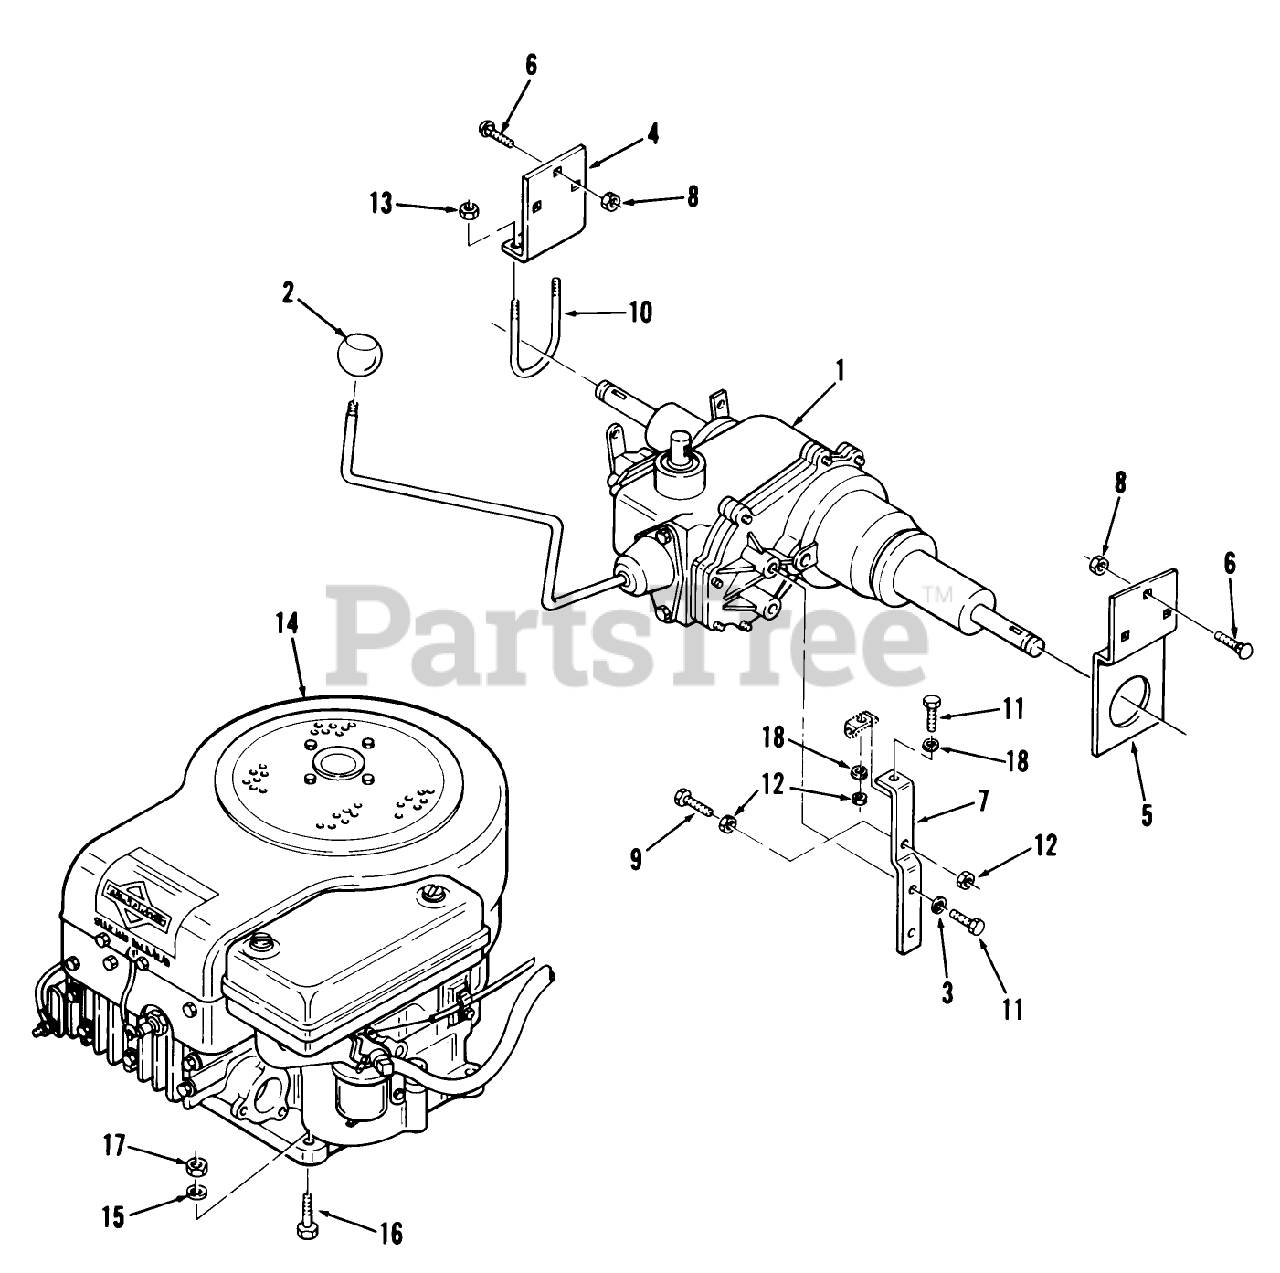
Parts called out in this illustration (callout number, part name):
1	Transmission-Peerless Mod. 669
2	SHIFT KNOB
6	CARRIAGE BOLT -4
14	Engine-8HP-BS Model 191707, Type 1136-01
14	Engine-11HP-BS Model 252707, Type 0151-01
15	WASHER 5/16 SAE
18	WASHER 5/16 SAE
